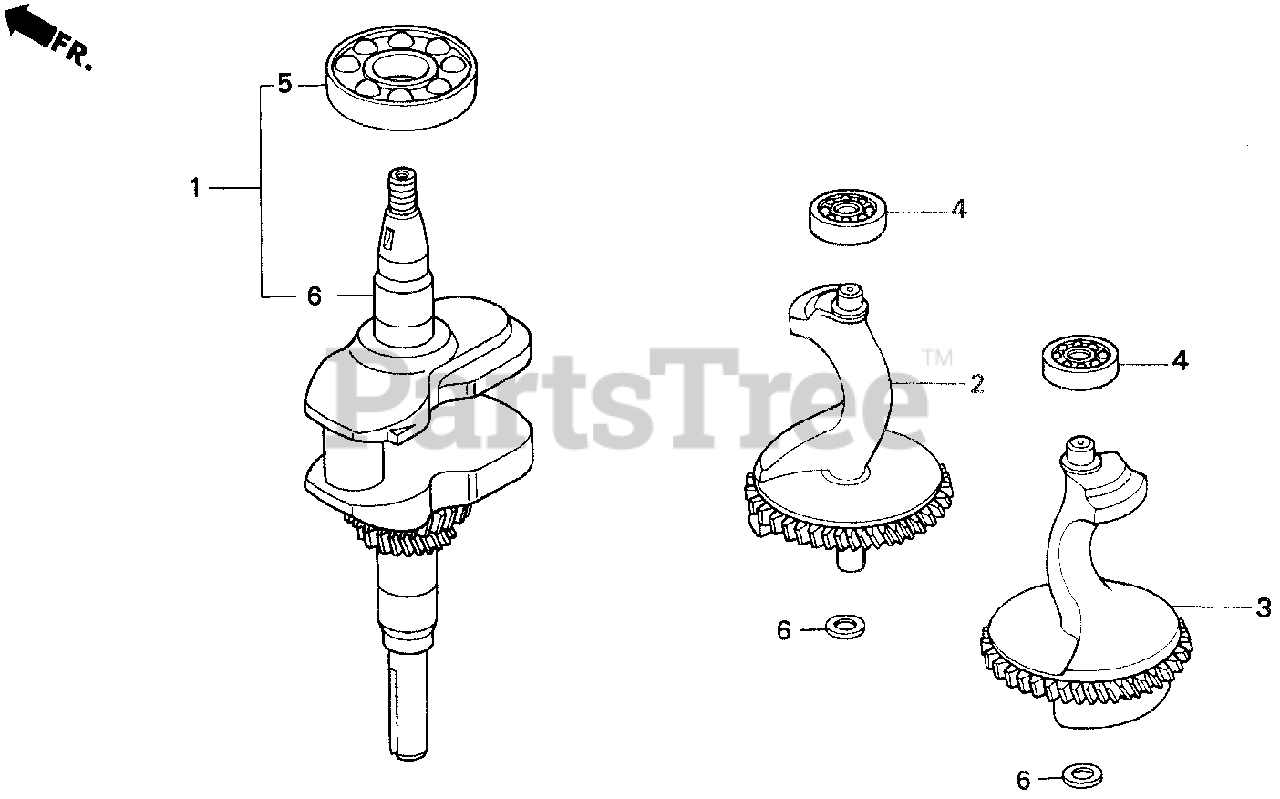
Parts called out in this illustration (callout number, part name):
1	CRANKSHAFT
2	WEIGHT A, BALANCER
3	WEIGHT B, BALANCER
4	BEARING, RADIAL BALL (6202)
5	BEARING, RADIAL BALL (6207)
6	CRANKSHAFT
6	WASHER, THRUST (14MM)
